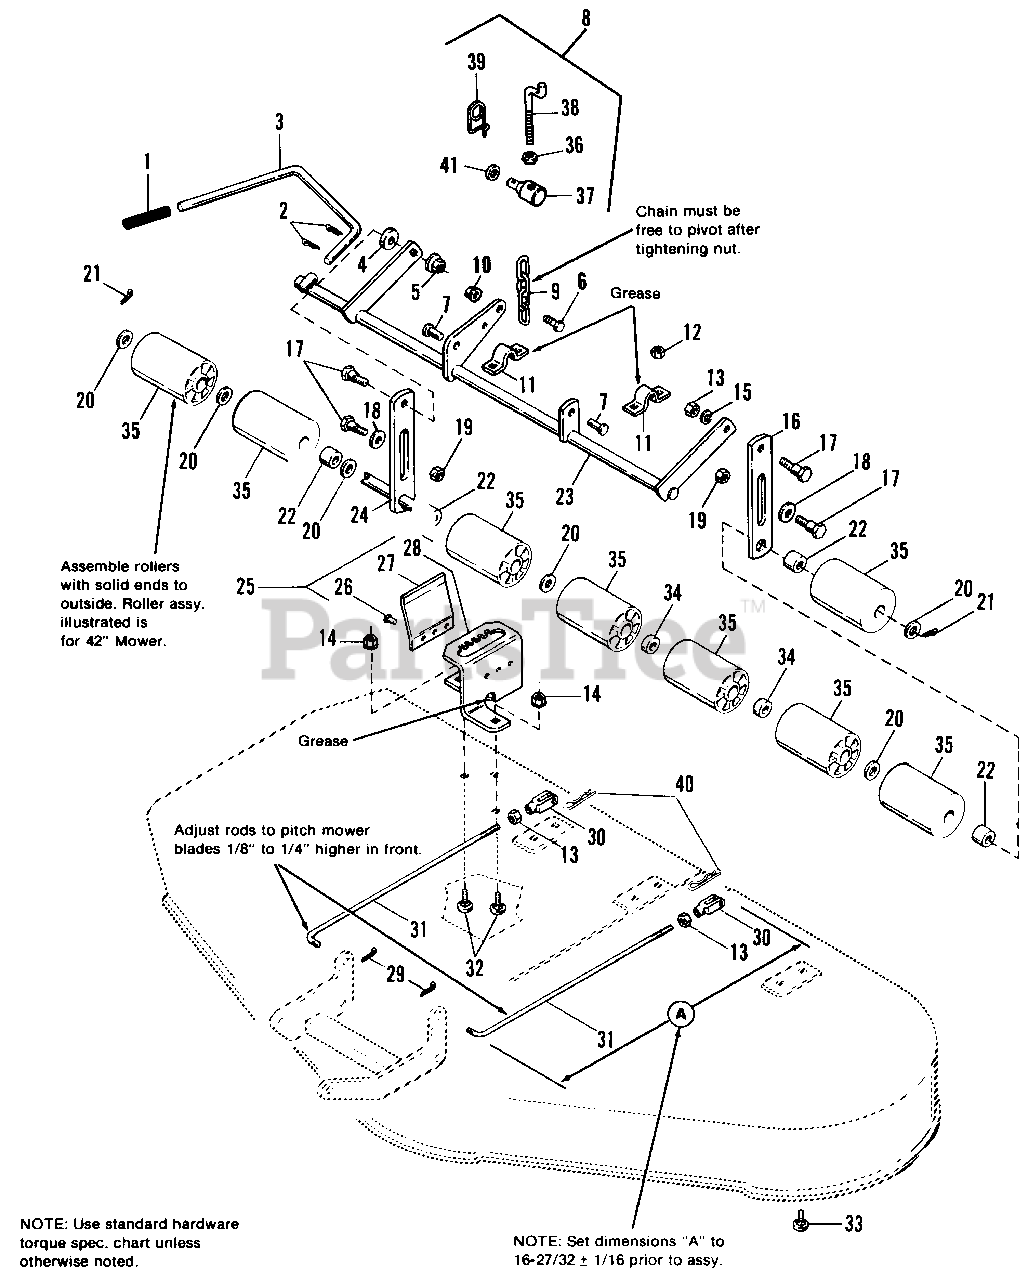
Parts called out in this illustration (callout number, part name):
2	PIN, Cotter, 1/8 x 1
3	LEVER, Control
4	WASHER, Plain, 13/32
5	LOCKNUT, Hex, Flange, Whiz, 3/8-16
6	CAPSCREW, Hex, 5/16-18 x 1
7	PIN, Clevis
8	ROD, Lift, (Incl. Ref. No. 36, 37, 38, 39, 41)
9	CHAIN, Lift
10	LOCKNUT, Flange, 5/16-18
11	STRAP (Qty. 3 on 48")
12	NUT, Hex, 5/16-18 (Qty. 6 on 48")
13	NUT, Hex, 3/8-16
14	NUT, Hex, Flange Whizlock, Full, 3/8-16
15	LOCKWASHER, 3/8
16	BAR, Roller
17	BOLT, Shoulder, 3/8-16 X 1.34
18	WASHER, Plain, 1/2
19	NUT, Esna, Lock, 3/8-16
20	WASHER, 25/32 x 1-1/4 (Qty. 9 on 48")
21	PIN, Cotter, 3/16 x 1
22	SPACER, .66 ID
23	ARM ASSY., Mower (42" only)
23	ARM ASSY., Mower (48" only)
24	SHAFT ASSY., Roller (42" only)
24	SHAFT ASSY., Roller (48" only)
25	QUADRANT ASSY. (Incl. Ref. Nos. 26, 27 & 28)
29	PIN, Cotter, 3/32 x 3/4
30	CLEVIS, Adj.
32	BOLT, Carriage, 3/8-16 x 3/4
33	BOLT, Carriage, 5/16-18 x 3/4 (Qty. 6 on 48")
34	SPACER (Used on 42" only)
35	ROLLERS (Qty. 10 on 48")
36	NUT, Jam, 5/16-18
38	ROD, Lift (Short)
39	CLIP, Pin, Safety
40	CLIP, Hair Pin
